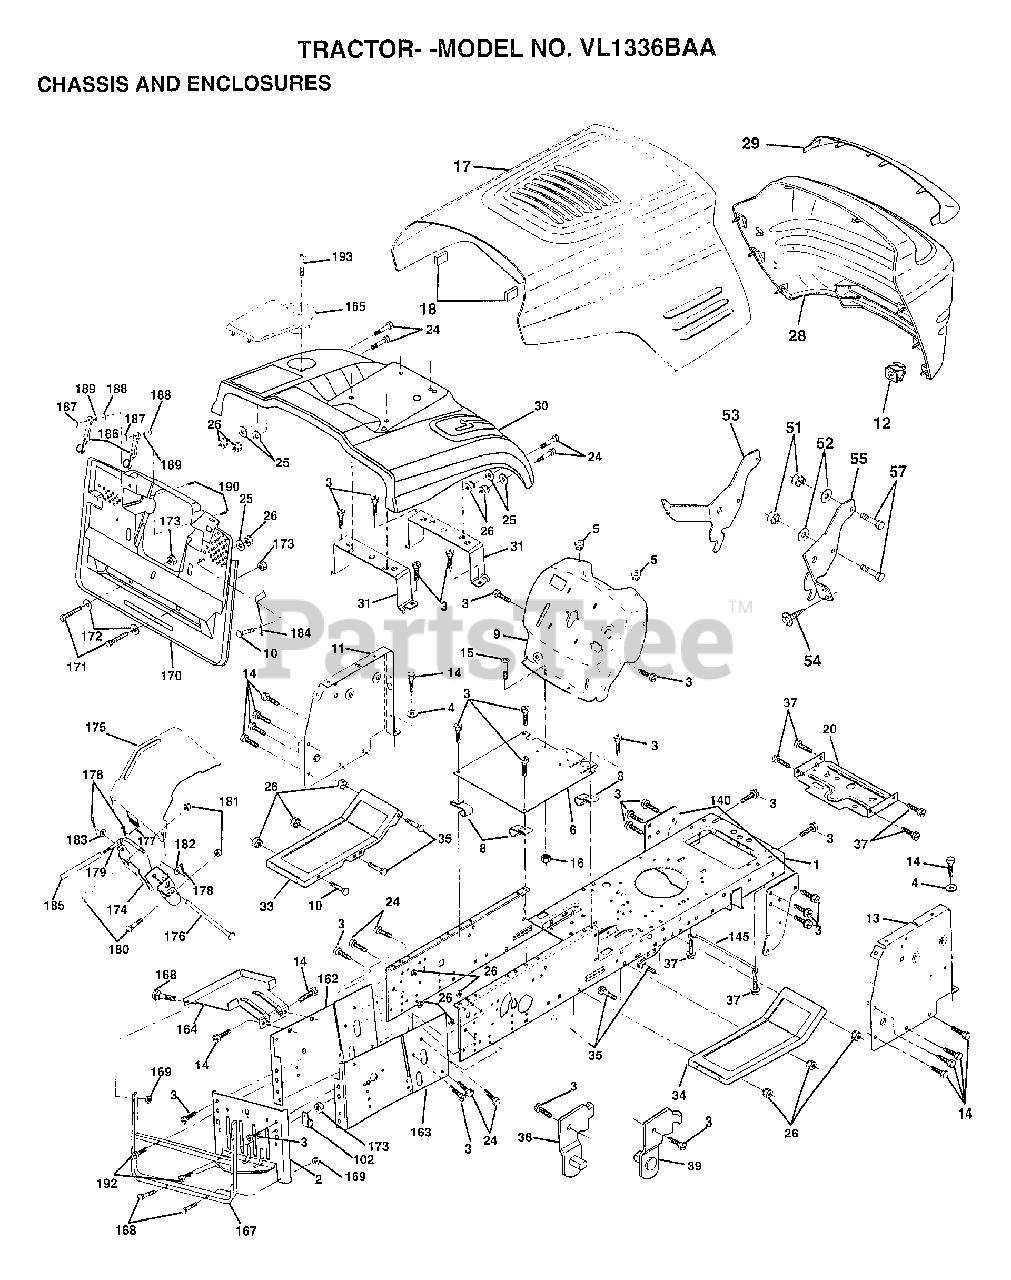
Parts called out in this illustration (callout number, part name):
1	CHASSIS.STAMPING
2	DRAWBAR.CRD
3	SCREW
4	WASHER
5	BUMPER-HOOD/DASH
6	SADDLE
8	"CLIP,INSULATOR"
9	DASH.SILKSCREEN
11	"PANEL-DASH,LH"
12	CLIP.TINNERMAN
13	"PANEL-DASH,RH"
14	SCREW LT
15	SCREW
17	HOOD
20	"PLATE-MTG,BATT/FU"
24	BOLT
25	WASHER
26	NUT
29	LENS.GRILLE
30	FENDER.GEAR.CRD.GREEN
31	BRKT.SUPT.FENDER.CRD
33	FOOTREST.LH.LT/GT
34	FOOTREST.RH.LT/GT
35	BOLT
37	SCREW LT
38	BRACKET ASM LH
39	BRACKET ASM RH
51	NUT
52	WASHER
53	BRACKET.GRILLE.LH
54	SCREW.HEX.WS.HD
55	BRACKET.GRILLE.RH
102	CLIP T
140	BRKT SUSPENSION
145	"ROD POVOT,CHASSIS"
162	BRKT.EXT.CHASSIS.LH.CRD
163	BRKT.EXT.CHASSIS.RH.CRD
164	SUPPORT.BATTERY.CRD
165	COVER.BATTERY.CRD.BLACK.LT
167	SUPT.ASM.BACKPLATE
168	BOLT-RD HD SQ NK
170	COVER.BACKPLATE.BLACK
171	BOLT.HEX.3/8-16X2-1/2
173	NUT
174	BRKT.SWITCH.FBI.CRD
175	GRUARD.DOOR.REAR.CRD
176	HINGE PIN
177	SPRING.COVER.LH
179	ROD.PIVOT.FBI.CRD
182	WASHER.385X.625
183	WASHER
184	BRKT.ACTUATOR.BAG.CRD
185	TUBE.LEVER.SWCH.FBI.CRD
186	LATCH ASSY.BAGGER
187	WELDNUT
188	WASHER #10
189	LOCKWASHER
190	SCREW
192	SCREW LT
193	SCREW LT
